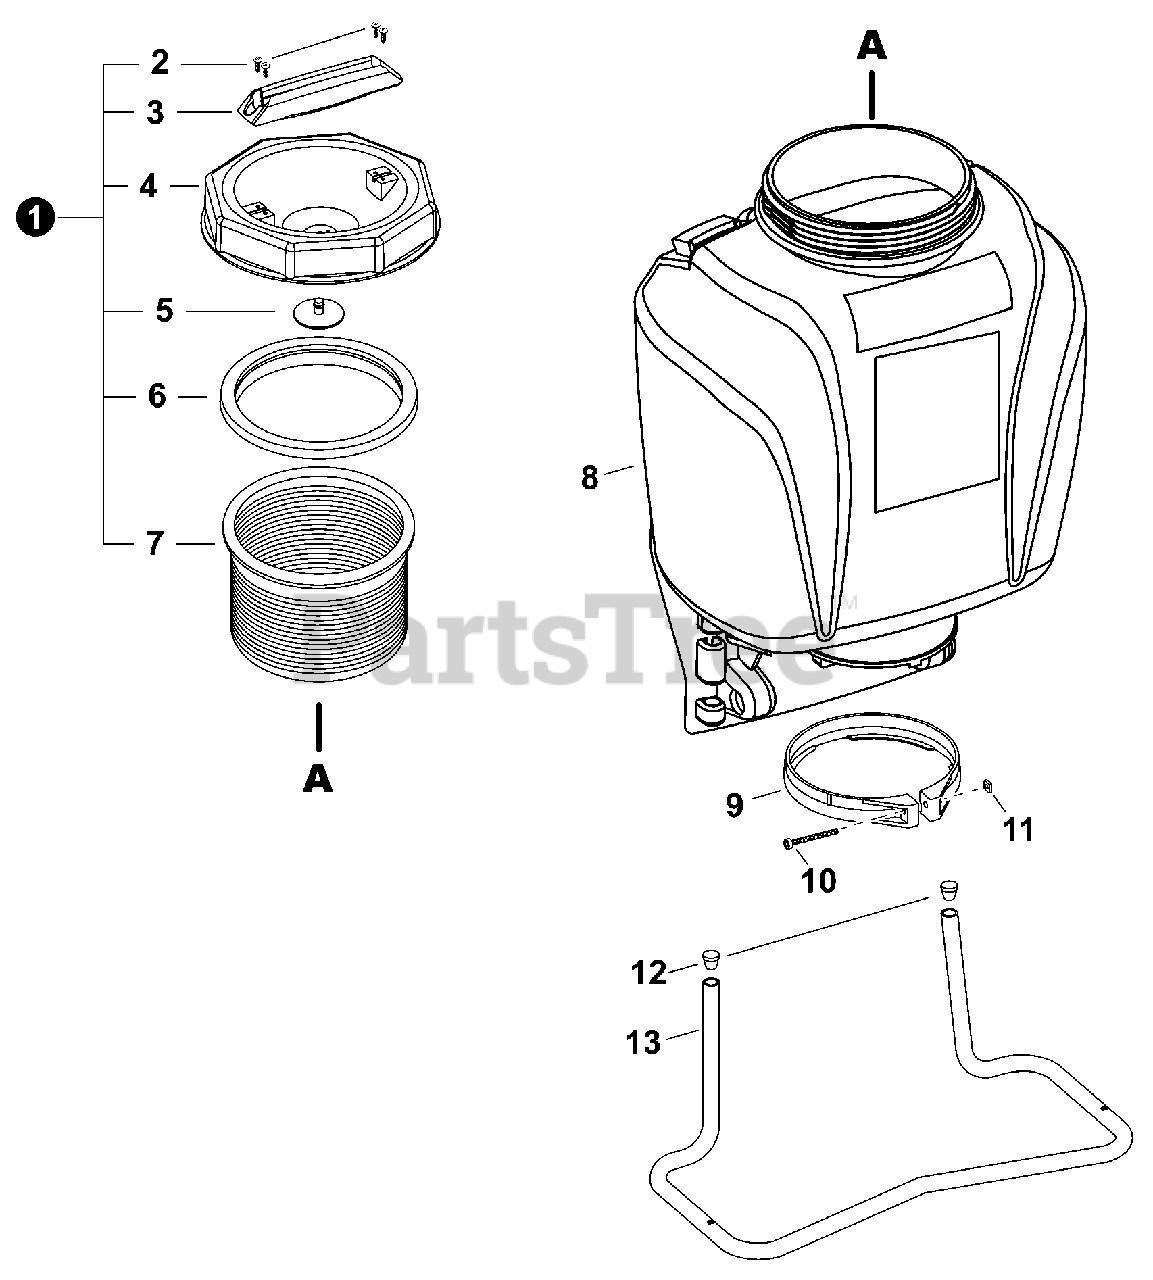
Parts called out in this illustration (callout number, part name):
1	CAP KIT, TANK
2	SCREW
3	HANDLE
4	CAP, TANK
5	VALVE, CHECK - CAP
6	GASKET, BASKET
7	BASKET, FILTER
8	TANK, SPRAYER
9	CLAMP, PUMP
10	SCREW, CLAMP
12	CAP, BASE
13	BASE, TANK
